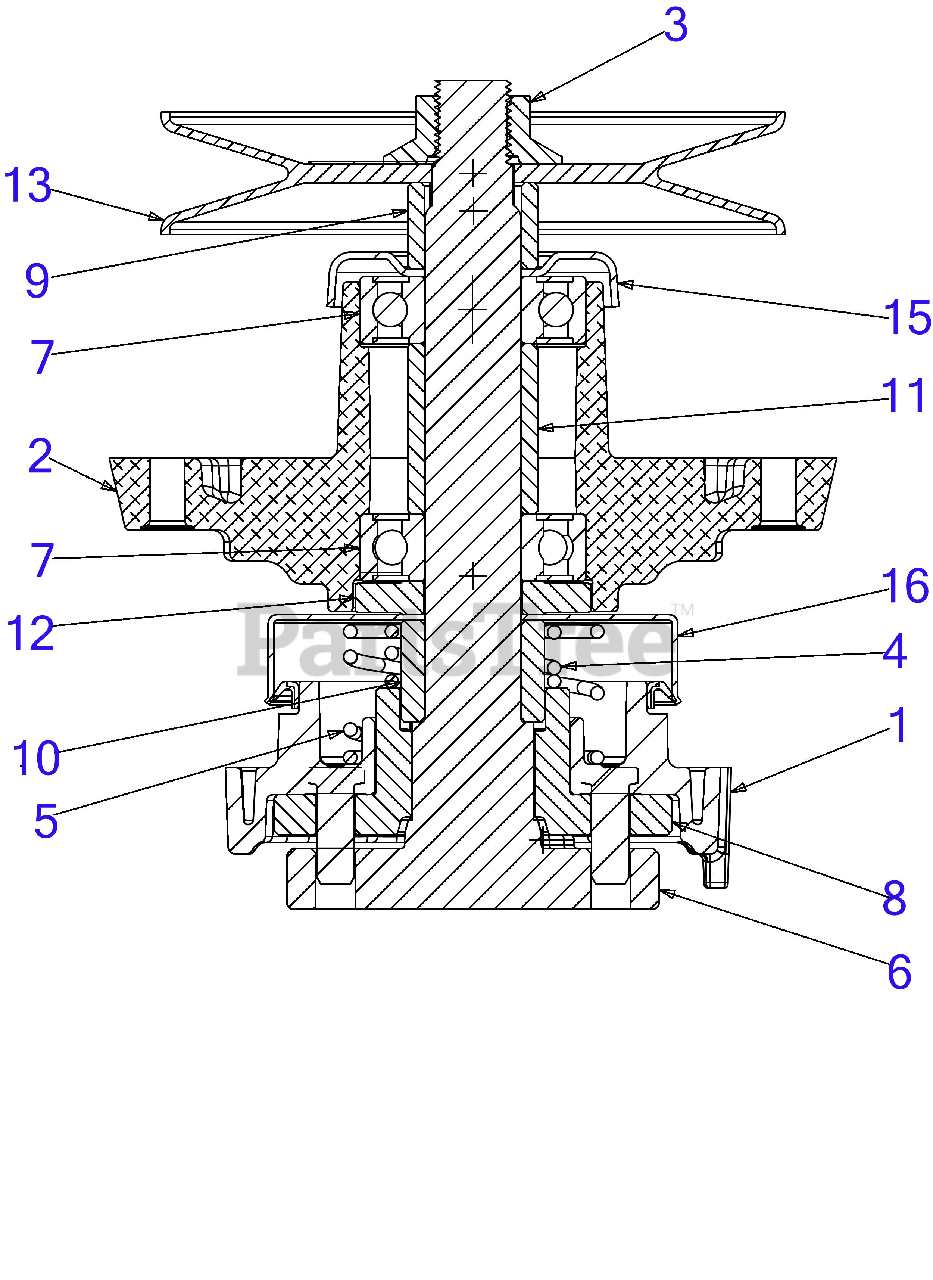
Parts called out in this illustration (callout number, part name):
1	SPINDLE COLLAR ASSEMBLY
2	SPINDLE HOUSING
3	FLANGE NUT 5/8-18
4	COMPRESSION SPRING
5	COMPRESSION SPRING
6	SPINDLE SHAFT
7	BALL BEARING
8	BLADE ADAPTER
9	PULLEY SPACER
10	SPACER
11	BEARING SPACER
12	SPINDLE SHIELD
13	SPINDLE PULLEY 5.2 DIA
15	SHIELD-BRG DECK
16	SEAL CAP
